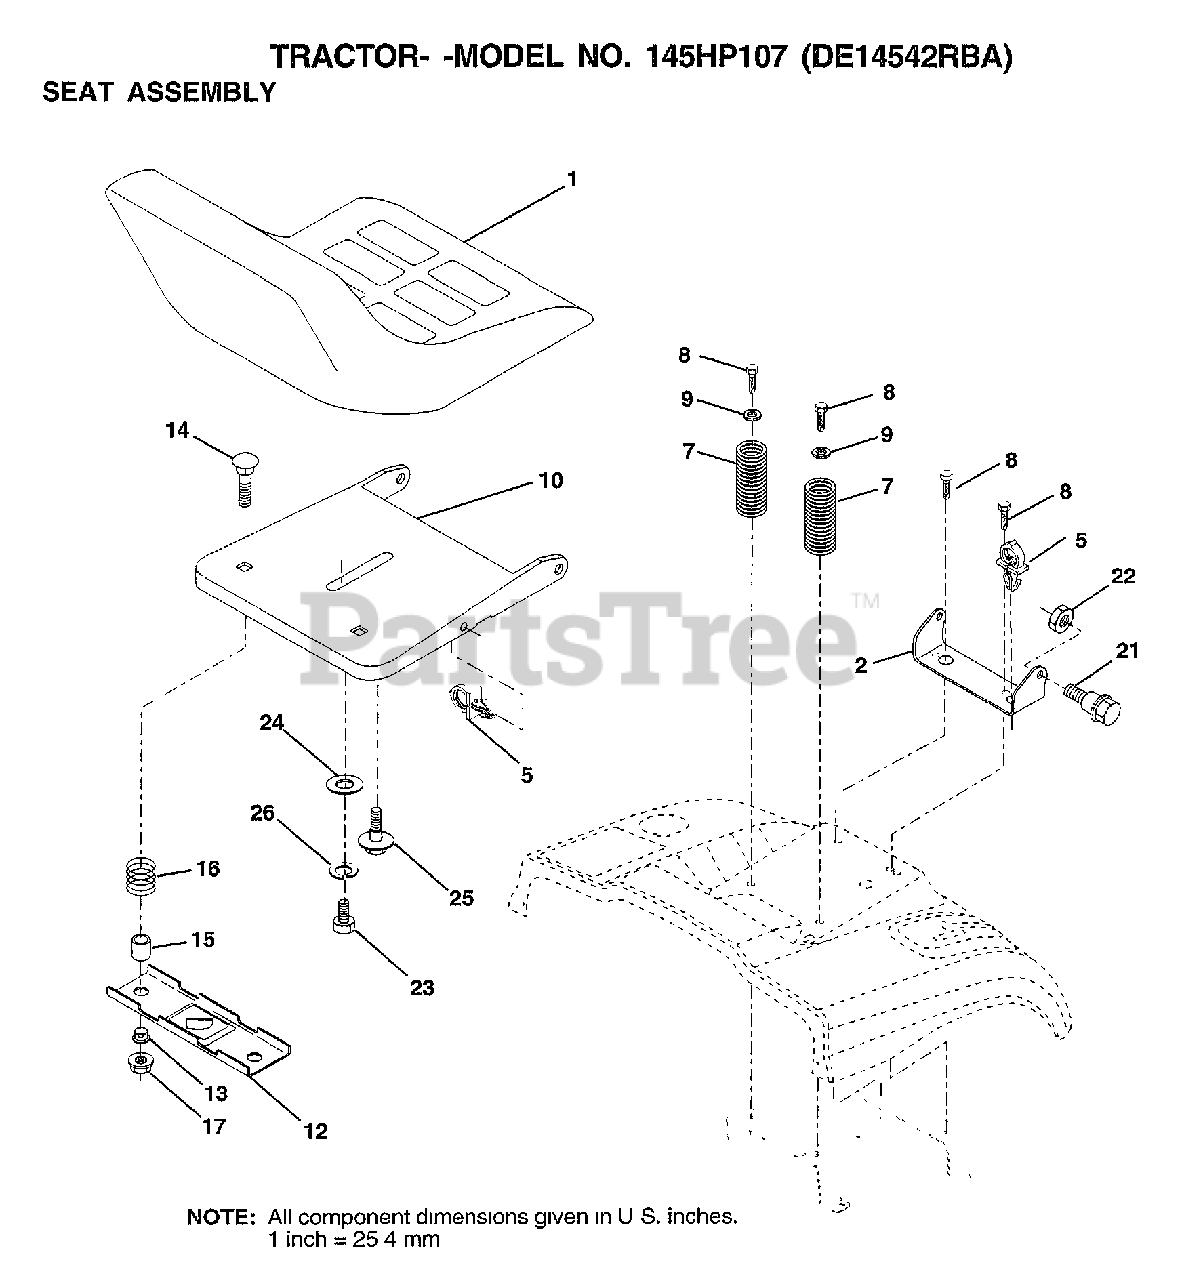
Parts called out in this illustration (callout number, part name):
2	BRACKET PVT SEAT
5	CLIP.PUSH-IN.HING
7	SPRING COMPRESSIO
8	SCREW
9	WASHER
10	PAN-SEAT
12	BRKT SWITCH
13	BUSHING
14	BOLT-RD HD SQ NK
15	SPLIT SPACER
16	SPRING
21	BOLT
22	NUT
23	BOLT
24	WASHER
25	"BOLT,SHOULDER"
26	LOCKWASHER
